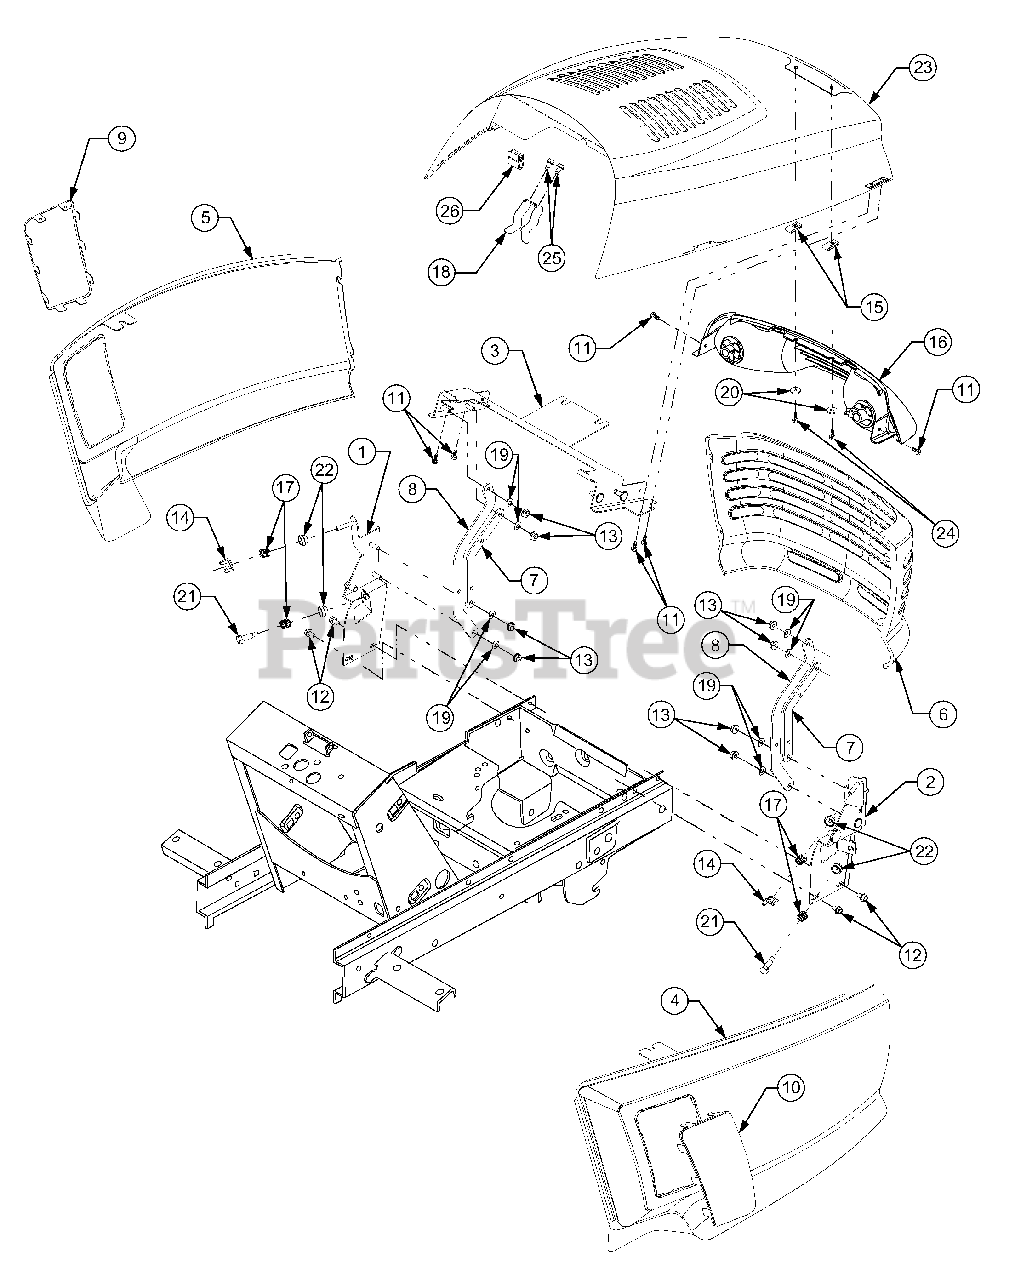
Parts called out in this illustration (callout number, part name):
1	Bracket, Grille LH
2	Bracket, Grille RH
8	Link, Long Hood
12	Screw, Hex Wash Hd Tapp, 1/4 x .50
13	Nut, Hex Flange Lock, 1/4-20
14	Nut, Wing, 1/4-20
15	Nut, U-Type Speed, #10
16	Headlight Assy
17	Spring, Compression, .50 OD x .50
18	Spring, Hood Latch
19	Washer, Spring, .265 x .562 x .025
20	Washer, Flat, .218 x .62 x .063
21	Bolt, Shoulder, .31 Dia x .75 Lg
22	Bushing, Tapered
23	Hood, Series 2000
24	Screw, Hex Tapp, 10-16 x .625
25	Screw, Hex Wash Hd Tapp, 1/4-14 x .5
26	Seal, Heat Baffle
